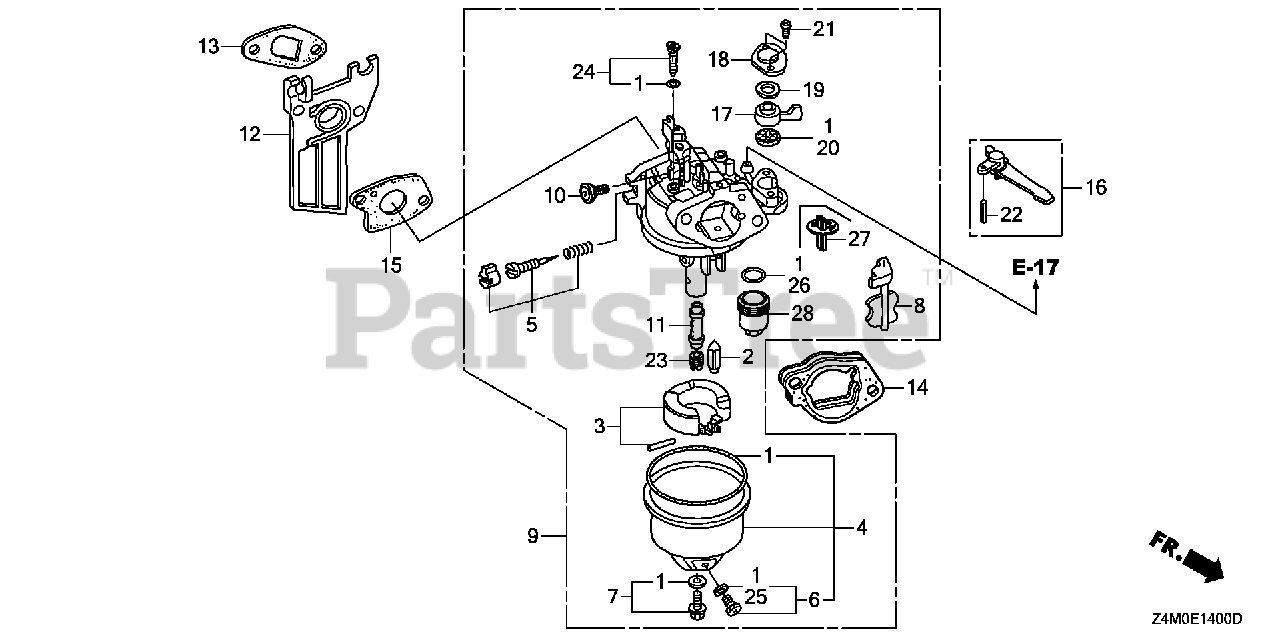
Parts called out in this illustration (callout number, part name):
1	GASKET SET (CARBURETOR NO.)
2	VALVE SET, FLOAT (CARBURETOR NO.) (SEAT NOT INCLUDED)
3	FLOAT SET
4	CHAMBER SET, FLOAT
5	SCREW SET (Honda Code 4219879). (CARBURETOR NO.)
5	SCREW SET
6	SCREW SET, DRAIN
7	SCREW SET (CARBURETOR NO.)
8	CHOKE SET
8	CHOKE SET (CARBURETOR NO.)
9	CARBURETOR ASSY. (BE61V A)
9	CARBURETOR ASSY. (BE66U A)
10	SCREW, THROTTLE STOP
11	NOZZLE, MAIN (CARBURETOR NO.)
11	NOZZLE, MAIN
12	INSULATOR, CARBURETOR
13	GASKET, INSULATOR
14	SPACER, CARBURETOR
15	GASKET, CARBURETOR
16	LEVER, CHOKE (STD)
17	LEVER, VALVE
18	PLATE, LEVER SETTING (CARBURETOR NO.)
19	SPRING, PETCOCK LEVER (CARBURETOR NO.)
20	GASKET, VALVE
21	SCREW, PAN (3X6)
22	PIN, SPRING (2X12)
23	JET, MAIN (#65)
23	JET, MAIN (#68)
23	JET, MAIN (#60)
23	JET, MAIN (#62)
24	JET SET, PILOT (#35)
24	JET SET, PILOT (#40) (ADVENTURE GREEN) (CARBURETOR NO.)
25	WASHER, PLAIN (6.2X10.7 DRAIN) (CARBURETOR NO.)
